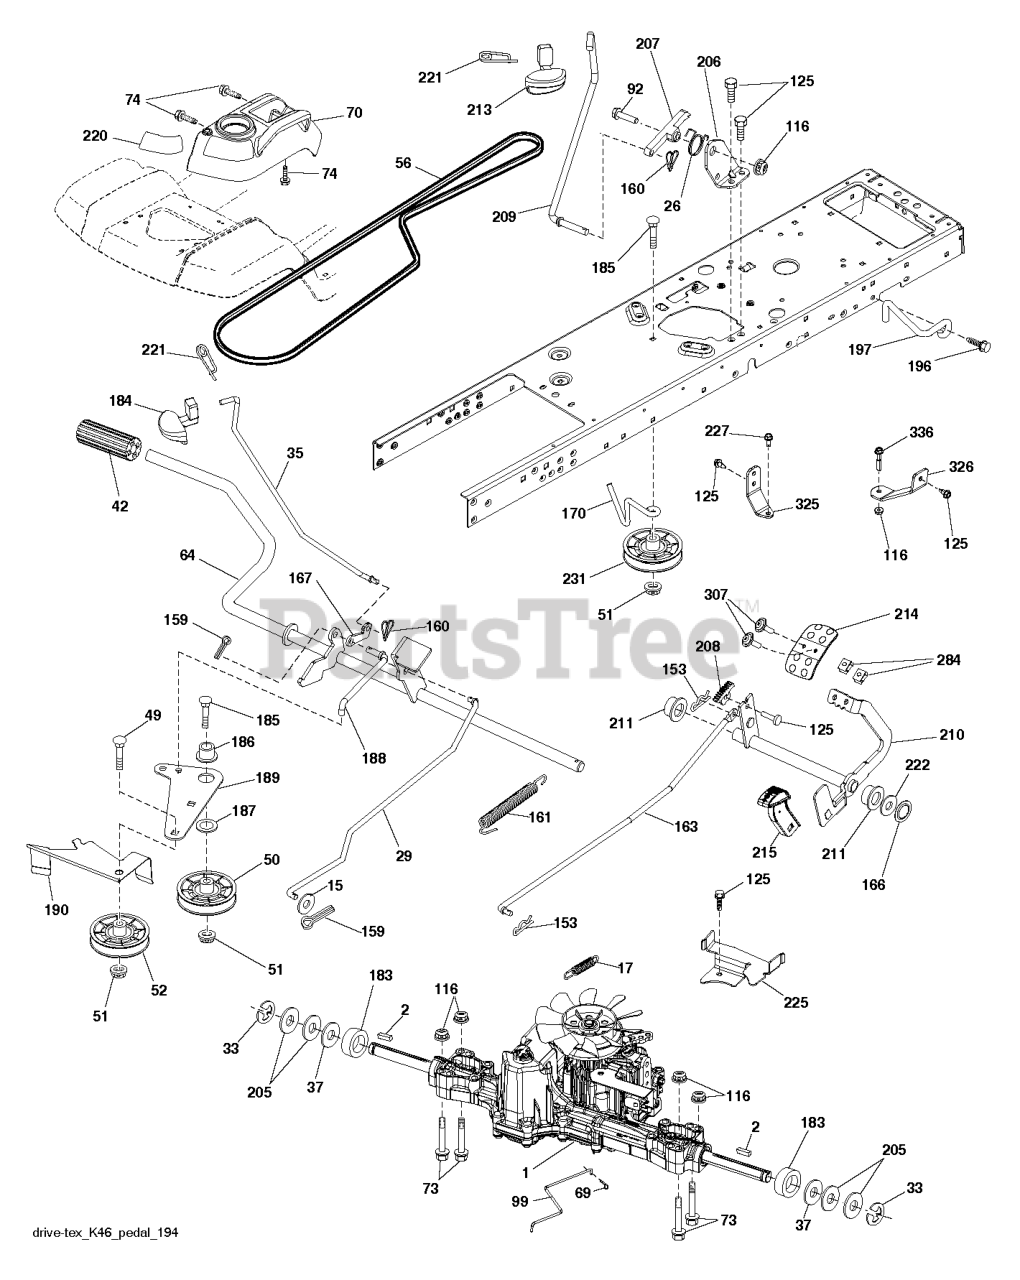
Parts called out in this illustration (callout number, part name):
1	RP TRANSAXLE (K46CR) ETC.PDL
2	SQUARE KEY
15	WASHER
17	SPRING.BRAKE.K46.GREEN
26	SPRING.RETURN.CRUISE
29	ROD.BRAKE.K46
35	ROD .BRAKE. PARKING. GT. HUSQ.
37	WASHER.HARDENED
42	PEDAL COVER T
50	IDLER.FLAT.910.OFFSET
51	NUT LOCK FLG 3/8-16 UNC
52	IDLER.V-GROOVE.910.OFFSET
56	V-BELT.MOWER.92.40.42/K46
64	SHAFT.ASM.PEDAL.BRK.CNTR
69	HAIRPIN.SOFT.ZINC.059X1.125
70	CONSOLE.ASM.RH.GT.FC.HUSQ
73	BOLT
74	SCREW.HI-LO.CONSOLE
92	BOLT
99	ARM.PIVOTING.TCRD.GEN2.5.BAGGE
116	NUT LOCK HEX FLANGE 5/16-18
125	SCREW
153	RETAINER M
159	COTTER PIN
160	RETAINER CLIP
161	SPRING, RETURN LT
163	ROD.CONTROL.K57R.K46
166	NUT.PUSH.625
167	LATCH.BRAKE.SPRING
170	KEEPER.CENTER SPAN.1.688
183	SPACER AXLE
184	HANDLE.PARKING.BRAKE.H (BLK)
186	SPACER.RETAINER
187	WASHER 12/32X2X10GA
188	LINK.CLUTCH.GROUND DRIVE.LONG
189	BELLCRANK.GROUND.DRIVE.TEX.
190	KEEPER.BELLCRANK.DRIVE
196	SCREW 3/8-16X1
197	BRKT.42.FCS.CLUTCH.ANTIROTATIO
206	BRACKET.MOUNT.CRUISE.LATCH
207	LATCH.CONTROL.CRUISE.TEX
208	GEAR.SECTOR.CONTROL.CR
209	ROD.CONTROL.CRUISE.GT.
210	ROCKER.ASM.PEDAL.CONTR
211	BEARING.NYLON
213	KNOB.CONTROL.CRUSIE.HU
214	PEDAL.FORWARD.HUSQVARNA.DEALER
215	PEDAL.COVER.REVERSE.CRD.X428BK
220	REFLECTOR.RH.TEX GT
221	RETAINER.SPRING.CLIP.H
222	WASHER 21/32 X 1-1/4 X 10 GA.
225	KEEPER.BELT.TRANSAXLE.K46
227	SCREW.THDROL.5/16-18X3/4.TTY
231	IDLER.V-GROOVE.1.688.OFFSET
284	NUT.U-CHNL.1/4-20.550DP.350PNL
307	SCREW.MACHINE.CR.1/4-20
325	TORQUE.STRAP.K46.LT.LH
326	BRCKT.PNT.TRQ.STP.46.18TIRE.RH
336	BOLT.5/16-18X1-3/4.FLANGED.HEX
